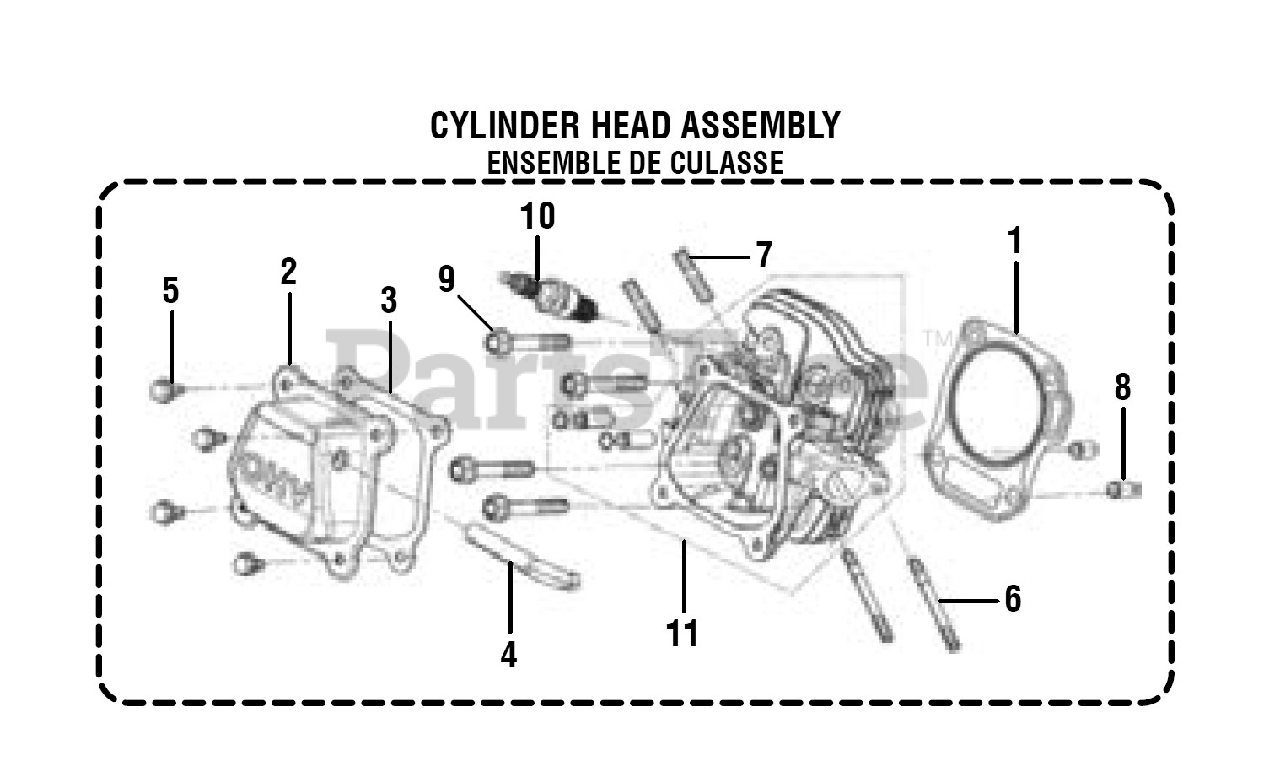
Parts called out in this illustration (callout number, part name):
1	Cylinder Head Gasket
2	Cylinder Head Cover Assembly
3	Cylinder Head Cover Gasket
4	Breather Tube
6	Stud
7	Stud
9	Cylinder Head Bolt
10	Spark Plug
11	Cylinder Head Assembly
